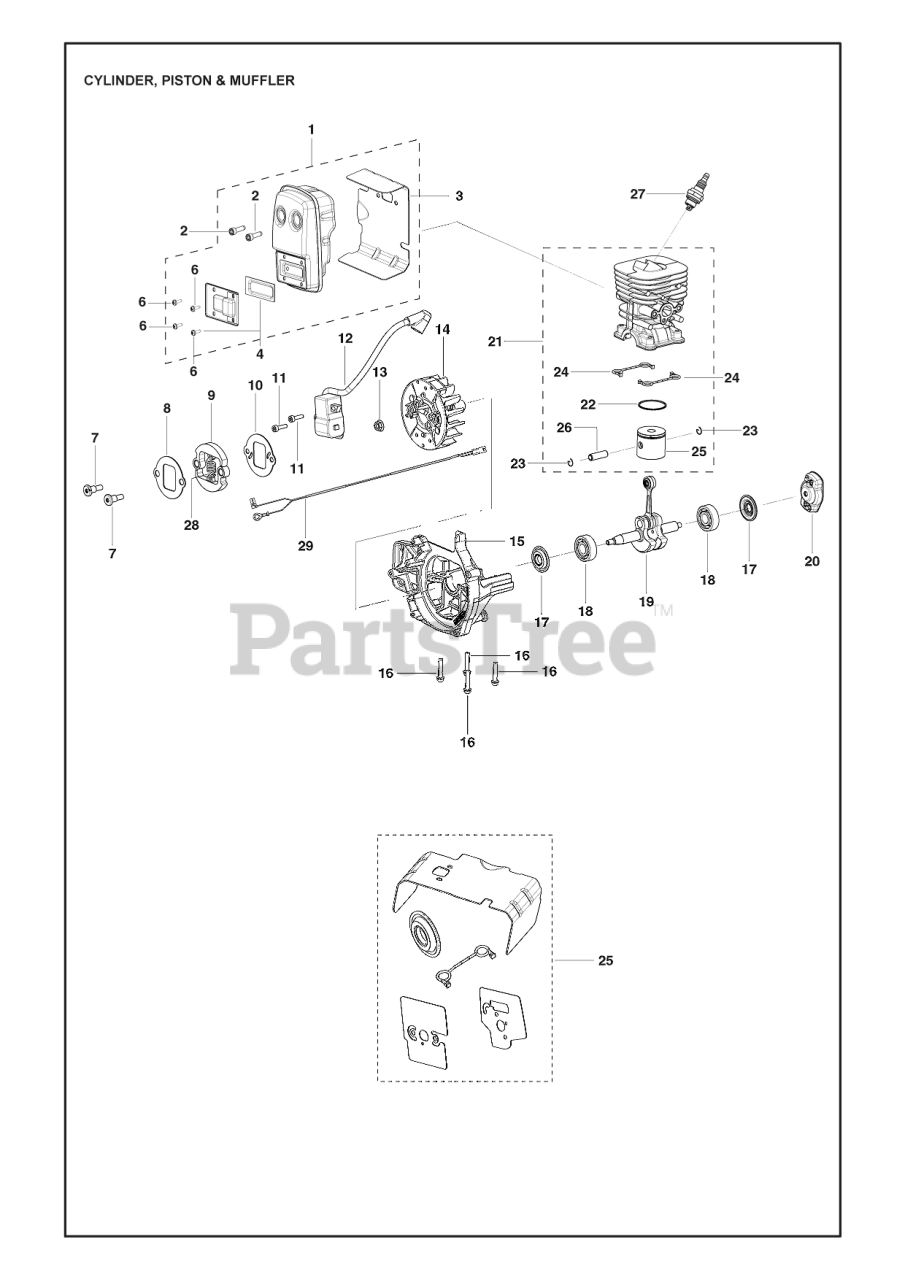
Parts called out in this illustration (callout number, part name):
1	MUFFLER KIT
2	BOLT MUFFLER
4	KIT SPARK ARRESTOR SCREEN
6	SCREW-6-19X5/16PLAST PA
7	SCREW CLUTCH
8	WASHER CLUTCH UPPER
9	CLUTCH ASSY
10	WASHER CLUTCH LOWER
11	SCREW M4 X .70 TT 16MM
12	IGNITION MODULE
13	FLANGE NUT
15	CRANKCASE CAST 128
16	SCREW-M5-0.8 X 25MM(TAP)
17	CRANKSHAFT SEAL
18	BEARING RADIAL BALL (6201)
19	CRANKSHAFT
20	ASSY STARTER PAWL
21	KIT PISTON & CYLINDER
22	RING PISTON
23	WRIST PIN RET.
24	SEAL CYLINDER
25	PISTON
26	PISTON PIN
27	SPARK PLUG
28	SPRING CLUTCH
29	ASSY MODULE LEAD WIRE
